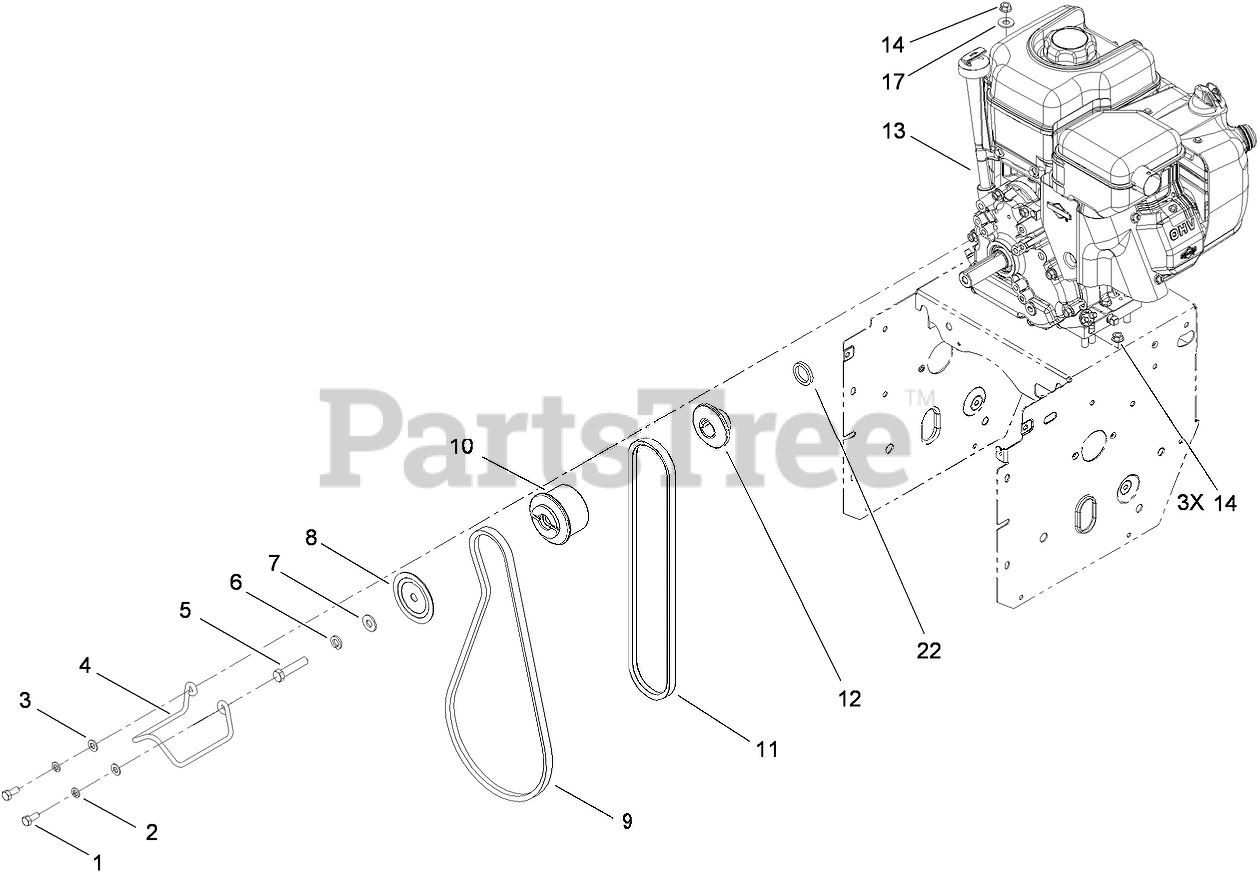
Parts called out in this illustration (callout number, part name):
1	SCREW-HH
2	WASHER-LOCK
3	WASHER-PLAIN
4	GUIDE-BELT
5	SCREW-HH
6	WASHER-LOCK
7	WASHER-FLAT
8	SHEAVE-HALF, IMPELLER
9	BELT-V
10	PULLEY-ENGINE, CENTER
11	V BELT-TRACTION
12	SHEAVE-HALF, TRACTION
14	NUT-HF
17	WASHER-FLAT
22	SPACER-HARDENED
